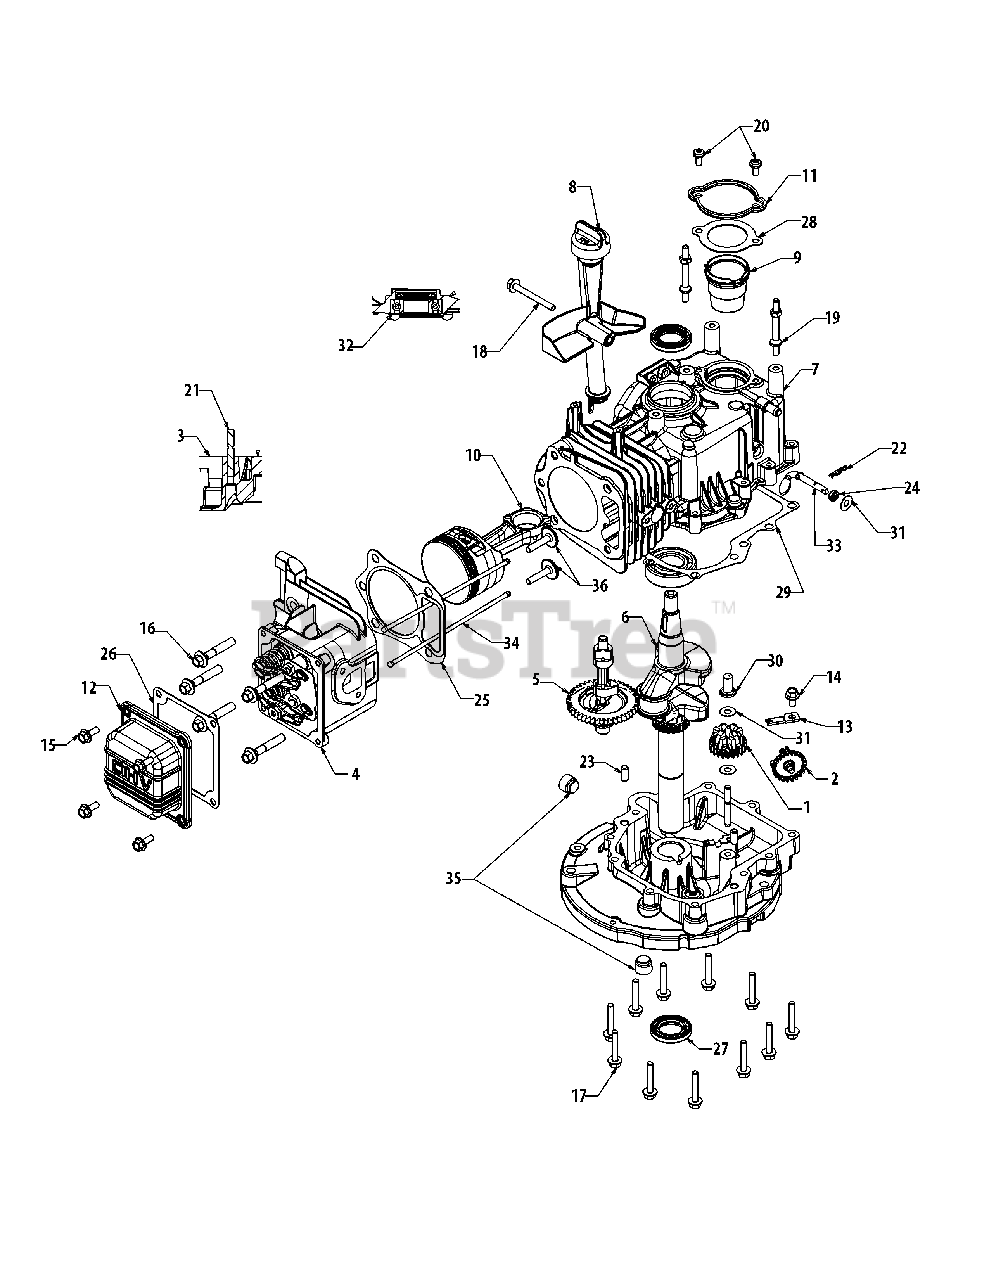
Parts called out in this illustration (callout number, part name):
1	Gear Asm-Gov 195
1	Gov Gear/Shaft Asm
1	Gov Arm Asm
2	Gear Asm-Oil Sling
3	Cover-Cr/Case Mach
4	Head Asm-Compl 195
4	Cylinder Head Kit
5	Camshaft Assembly
6	Cr/Shf-End 195 25M
7	Short Block Asm
8	Dipstick Asm-Engin
8	Dipstick Asm-Oil
9	Breather Asm
10	Piston Asm-Engine
11	Cover-Breather 195
12	Cover-Valve Ohv 19
13	Bracket-Support Oi
14	Hhflg-M6-1:12 Cl8.
15	Hhflg-M6-1:16 Cl8.
16	Hhflg-M8-1.25:45:C
17	Hhflg-M6-1:35 Cl8.
18	Hhflg-M6-1:50:Cl5.
19	Stud-M6-1:40 Lg
20	Screw-Machine M6-1
21	Shaft-Governor 6.3
22	Pin-Cotter 1.2 X 2
23	Pin-Dowel 7 X 16
24	Seal-Oil 11 X 4 X
25	Gasket-Head 195
26	Gasket-Valve Cover
27	Seal-Oil 41.25 X 2
28	Gasket-Breather 19
29	Gasket-Cr/Case 195
30	Cap-Push Gov 195
31	Washer-Flat 6.8 X
32	Pto Shaft Ball Bearing
33	Rod-Gov Control
34	Tube-Push Rod 195
34	Kit-Push Rod
35	Plug-Engine 3/8 Np
36	Tpt-Cam 195
